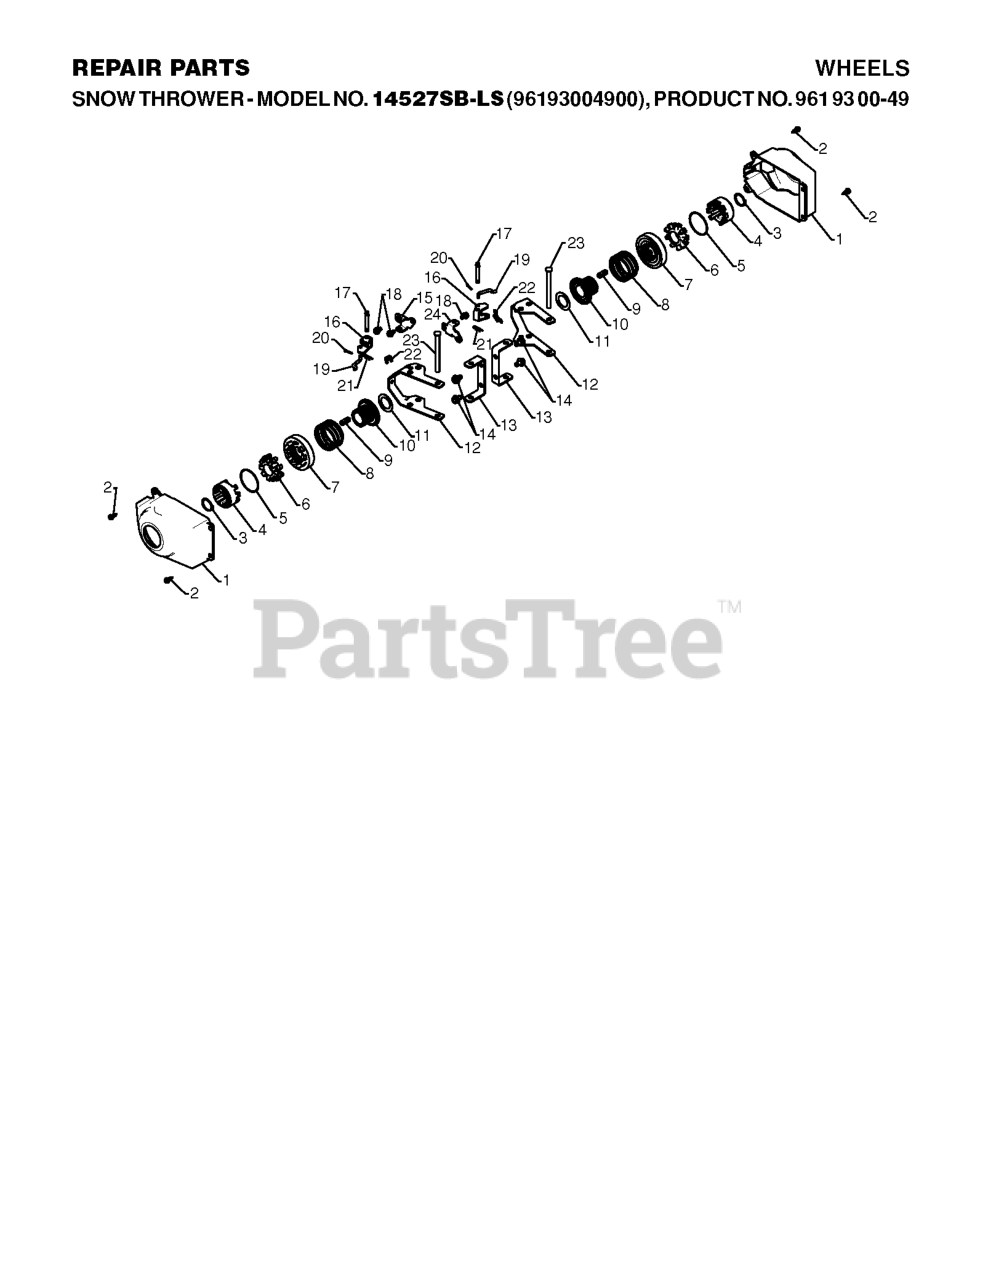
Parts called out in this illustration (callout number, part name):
1	COVER, POWER STEERING
2	SCREW, HEX HEAD, TAPPING
4	RP.DRIVER WHEEL
5	RING, WIRE RETAINER
6	LOBE WHEEL
7	RP.SLIDE.CLUTCH
8	SPRING, CLUTCH SLIDE
9	KEY, SQUARE 1/4 X .875
10	RP.LOBE.AXLE
11	WASHER TRUST 1"
12	YOKE, STEERING
13	BRACKET.STEER.PNT.BLACK
14	Screw 5/16-18 x 1/2 Hex, Self Tapping 5/16-18 x 1/2
15	BRKT.STEER.PIVOT.RH
16	BELLCRANK.STEER
17	PIN, STEERING BELLCRANK
18	SCREW 1/4X20
19	LINK.STEER.YOKE
20	RETAINER CLIP
21	RETAINER CLIP PM
22	SPRING LATCH
23	PIN, STEERING LEVER
24	BRACKET.STEER.PIVOT.LH.YZ
